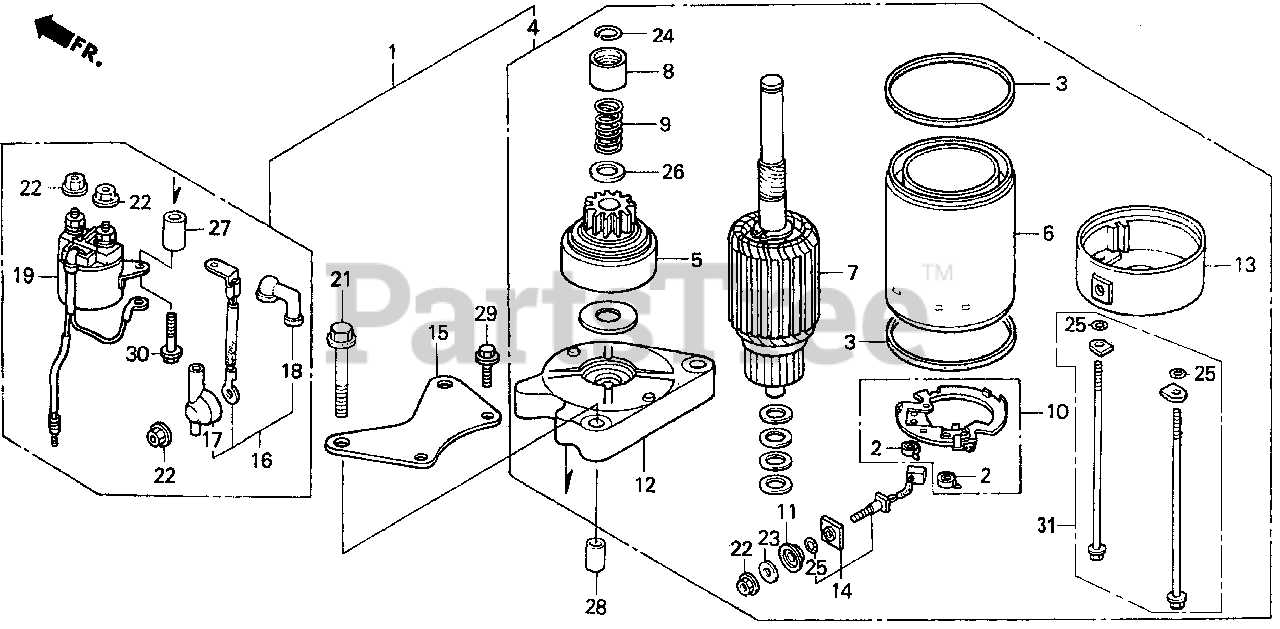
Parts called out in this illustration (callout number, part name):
1	MOTOR ASSY., STARTER
2	SPRING, CARBON BRUSH
4	MOTOR UNIT, STARTER
8	PIECE, STOPPER
9	SPRING, RETURN
10	HOLDER, BRUSH
12	BRACKET, FR.
13	BRACKET, RR.
14	UNIT, TERMINAL
15	STAY, STARTER MOTOR
16	WIRE, MAGNET SWITCH
17	COVER, STARTER TERMINAL
18	COVER, MAGNETIC SWITCH TERMINAL
19	SWITCH ASSY., STARTER MAGNETIC
21	BOLT, FLANGE (8X45)
22	NUT-WASHER (6MM)
23	WASHER (6MM)
24	CIRCLIP (14MM)
27	COLLAR, DISTANCE
28	PIN A, DOWEL (10X16)
29	BOLT, FLANGE (6X16)
30	BOLT, FLANGE (6X25)
31	BOLT SET, SETTING
